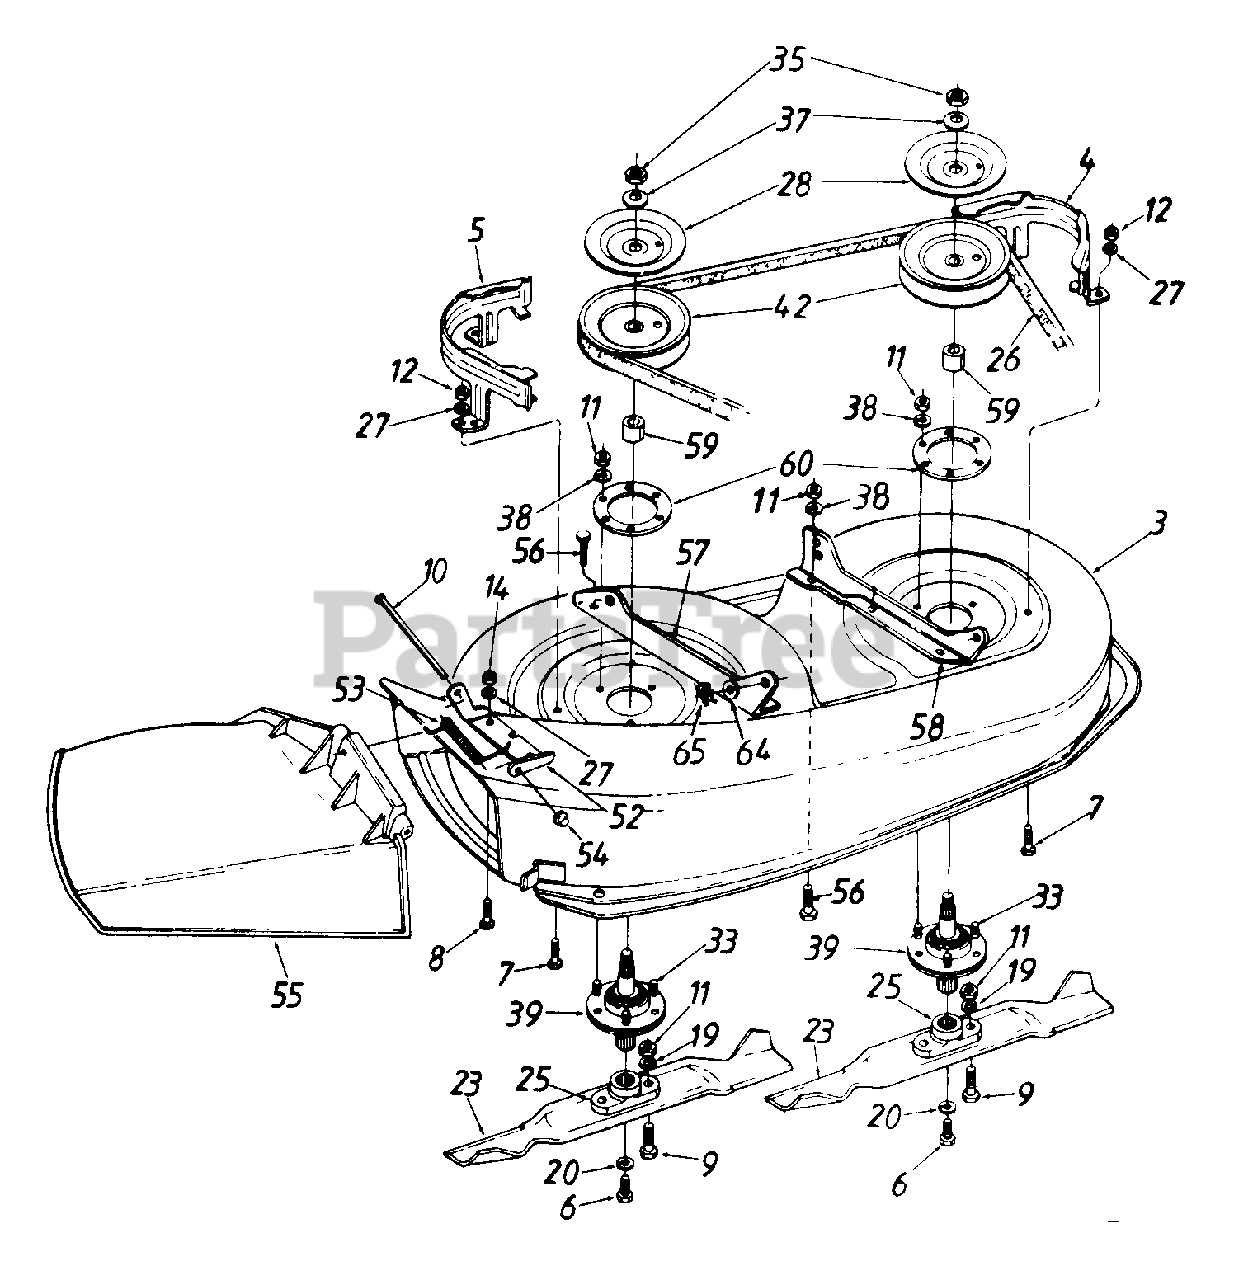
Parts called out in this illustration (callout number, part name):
3	36" Deck Ass'y.
7	Hex Bolt 1/4-28 x .62" Lg. (36" Deck)
8	Truss Mach. Scr. 1/4-20 x .75" (36" Deck)
9	Hex Bolt Special 5/16-24 x 1.0"
10	Hinge Pin
11	Hex Nut 5/16-24 Thd.
12	Hex Nut 1/4-28 Thd. (36" Deck)
14	Hex Nut 1/4-20 Thd.
19	L-Wash. 5/16" I.D.
20	L-Wash. 3/8" I.D. - H.D.
23	High-Lift Blade (36" Deck)
25	Blade Adapter
26	"V" - Belt (36" Deck)
27	Bell-Wash. 1/4" I.D.
28	Brake Disc
33	Rib Neck Bolt 5/16-24 x .84" Lg. (36" Deck)
35	Hex Jam Nut 5/8-18 Thd.
37	L-Wash. 5/8" I.D.
38	Bell-Wash. .345" I.D. x .88" O.D.
39	Blade Spindle Ass'y. Comp.
42	5" Dia. Pulley
52	Hinge Mtg. Brkt.
53	Torsion Spring
54	Push Nut
55	Chute Ass'y. Comp.
56	Hex Bolt 5/16-24 x .75" Lg.
64	Fl-Wash. .406" I.D. x .73" O.D.
65	Hairpin Clip 3/8" Dia.
